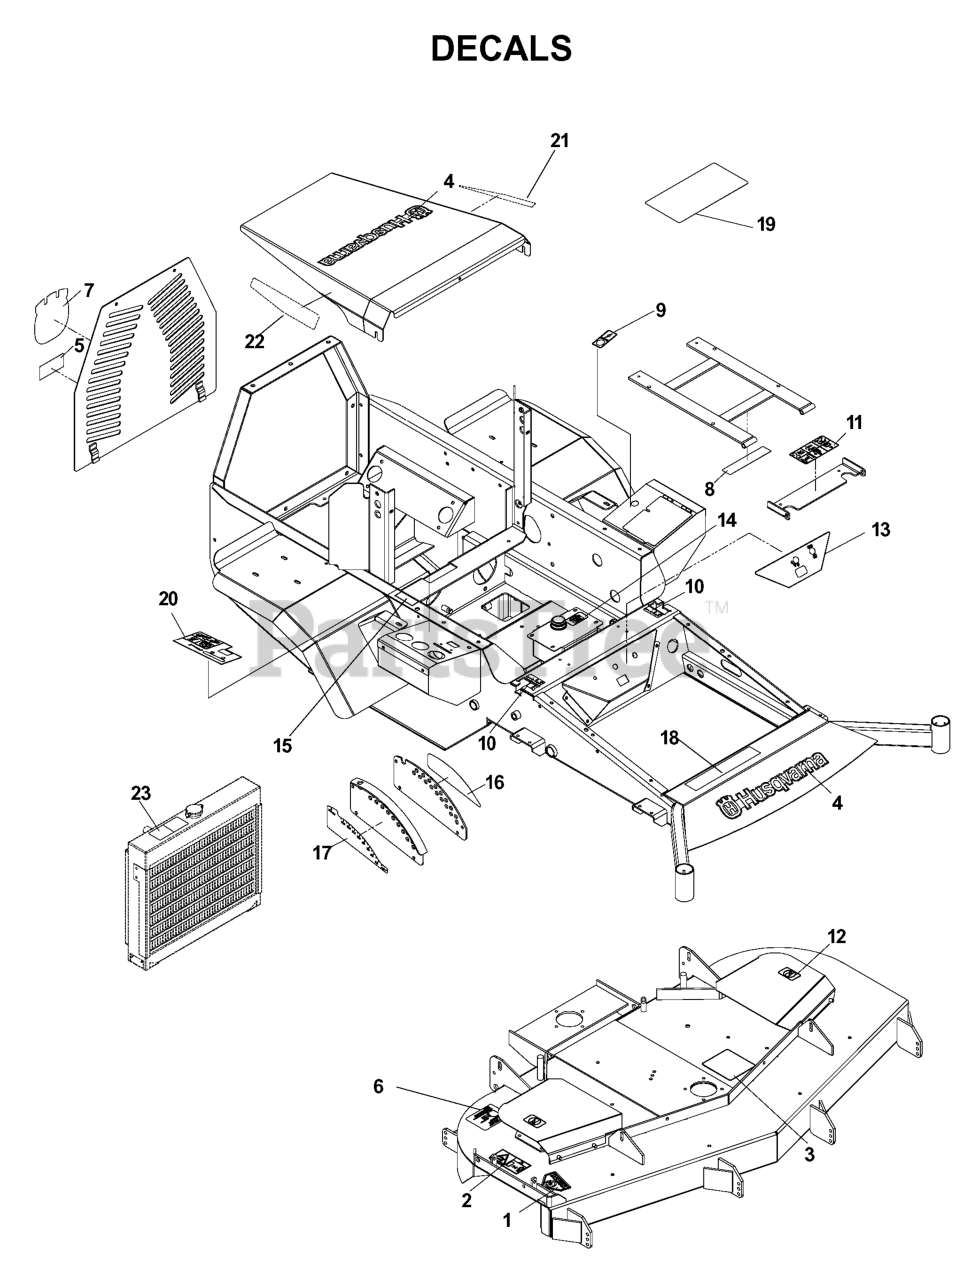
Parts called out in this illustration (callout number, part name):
1	DECAL, CPSC
2	DECAL, EURO SEVERING
3	DECAL, BELT ROUTING
4	DECAL, HUSQVARNA 17.5"
5	DECAL, BELT DRIVE
6	DECAL, ANTI SCALP
7	DECAL, LGE CROWN 7X6"
8	EURO DECAL-BATTERY WARNIN6
9	DECAL, 12V
10	DECAL, MOTION CONTROL
11	DECAL, EURO WARNING
12	DECAL, NO STEP
13	DECAL, FRONT CONSOLE
14	DECAL, MOBIL 1
15	FUEL VALVE DECAL
19	DECAL, SERVICE
20	DECAL, RT CONSOLE
21	DECAL, 34 TURBO LH
22	DECAL, 34 TURBO RH
23	DECAL, HOT
539100128	DECAL, EXHAUST
539106255	DECAL BZE7234D
